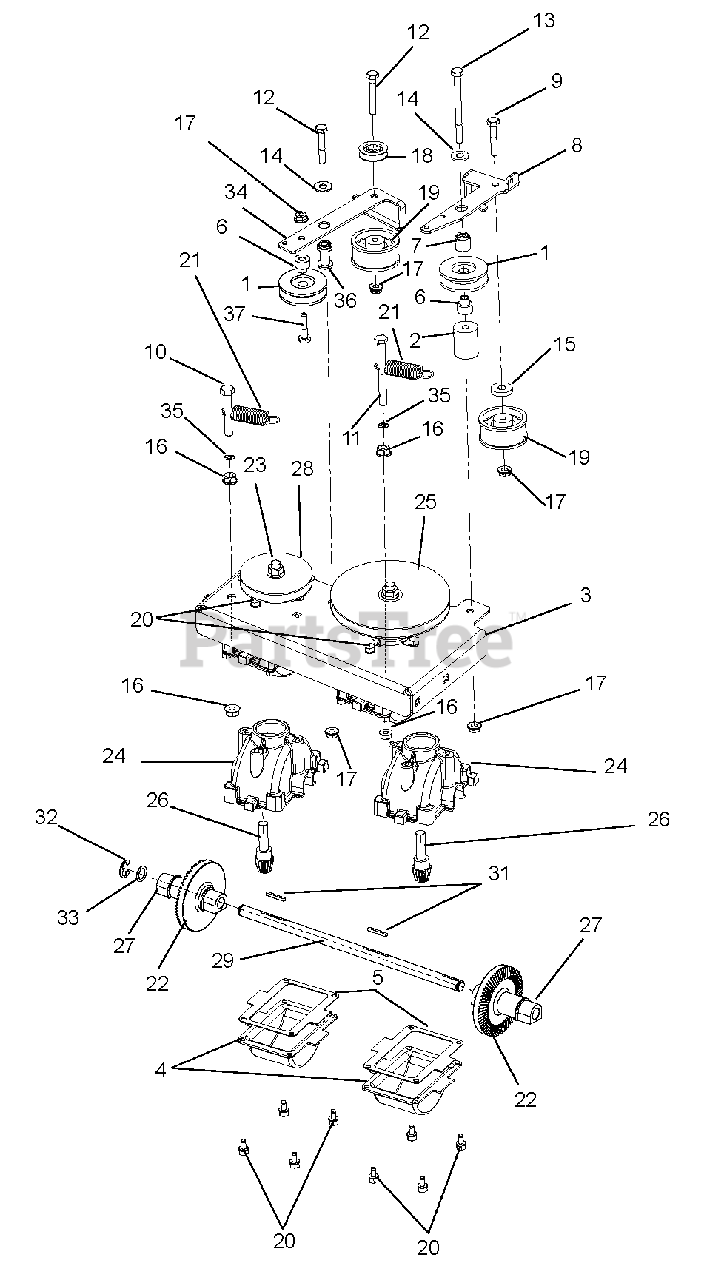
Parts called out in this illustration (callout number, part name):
1	IDLER, 3L FRONT SIDE .38X1.875
2	SPACER, REVERSE IDLER
3	PLATE, TRANSMISSION MOUNT
4	SUMP, GEARBOX
5	GASKET, TRANSMISSION
6	SPACER, V-IDLER PULLEY
7	SPACER, IDLER ARM
8	BRKT-TRANS IDLER ARM
9	@BLT-HEX .25-20X1.50 GR5 YWZC
10	@BLT-HEX .31-18X2.50 GR5 YWZC
11	@BLT-HEX .31-18X3.50 GR5 YWZC
12	@BLT-HEX .25-20X1.75 GR5 YWZC
13	@BLT-HEX .25-20X3.25 YWZC
14	@WSHR-FL-STL.312X.734X.065 YWZ
15	WSHR-FL-STL .328X.87X.179 YWZC
16	@NUT-SPNLK-FLG .312-18 YWZC
17	@NUT-LK-TOP-FLG .25-20 YWZC
18	PULLEY, CABLE
19	PULLEY, ILDER .25X1.875X.97
20	SCR-TAP 10-24X.375 PRE-COAT 80
21	SPRG, TENSION .063X.625X2.50
22	GEAR, BEVEL (CU INFL, KEYWAY)
23	@NUT-LK-TOP-FLG .38-16 YWZC
24	HOUSING, WBLM GEAR BOX
25	PULLEY, WAW REVERSE INPUT
26	PINION, GEARBOX INPUT
27	BUSHING, TRANS OUTPUT SHAFT
28	PULLEY, WAW INPUT
29	SHAFT-TRANS OUTPUT
30	KIT, WAW TRANSMISSION SHAFT
31	KEY, 1/8 X 1/8 X 1.0
32	RG-RTNG-EXT .500X.042 (E)
33	WASHER, .500X.750X.020 THRUST
34	ARM, DOUBLE ACTING IDLER
35	NUT-PUSH .312
36	PIVOT, IDLER
37	@BLT-HEX .25-20X1.25 GR5 YWZC
